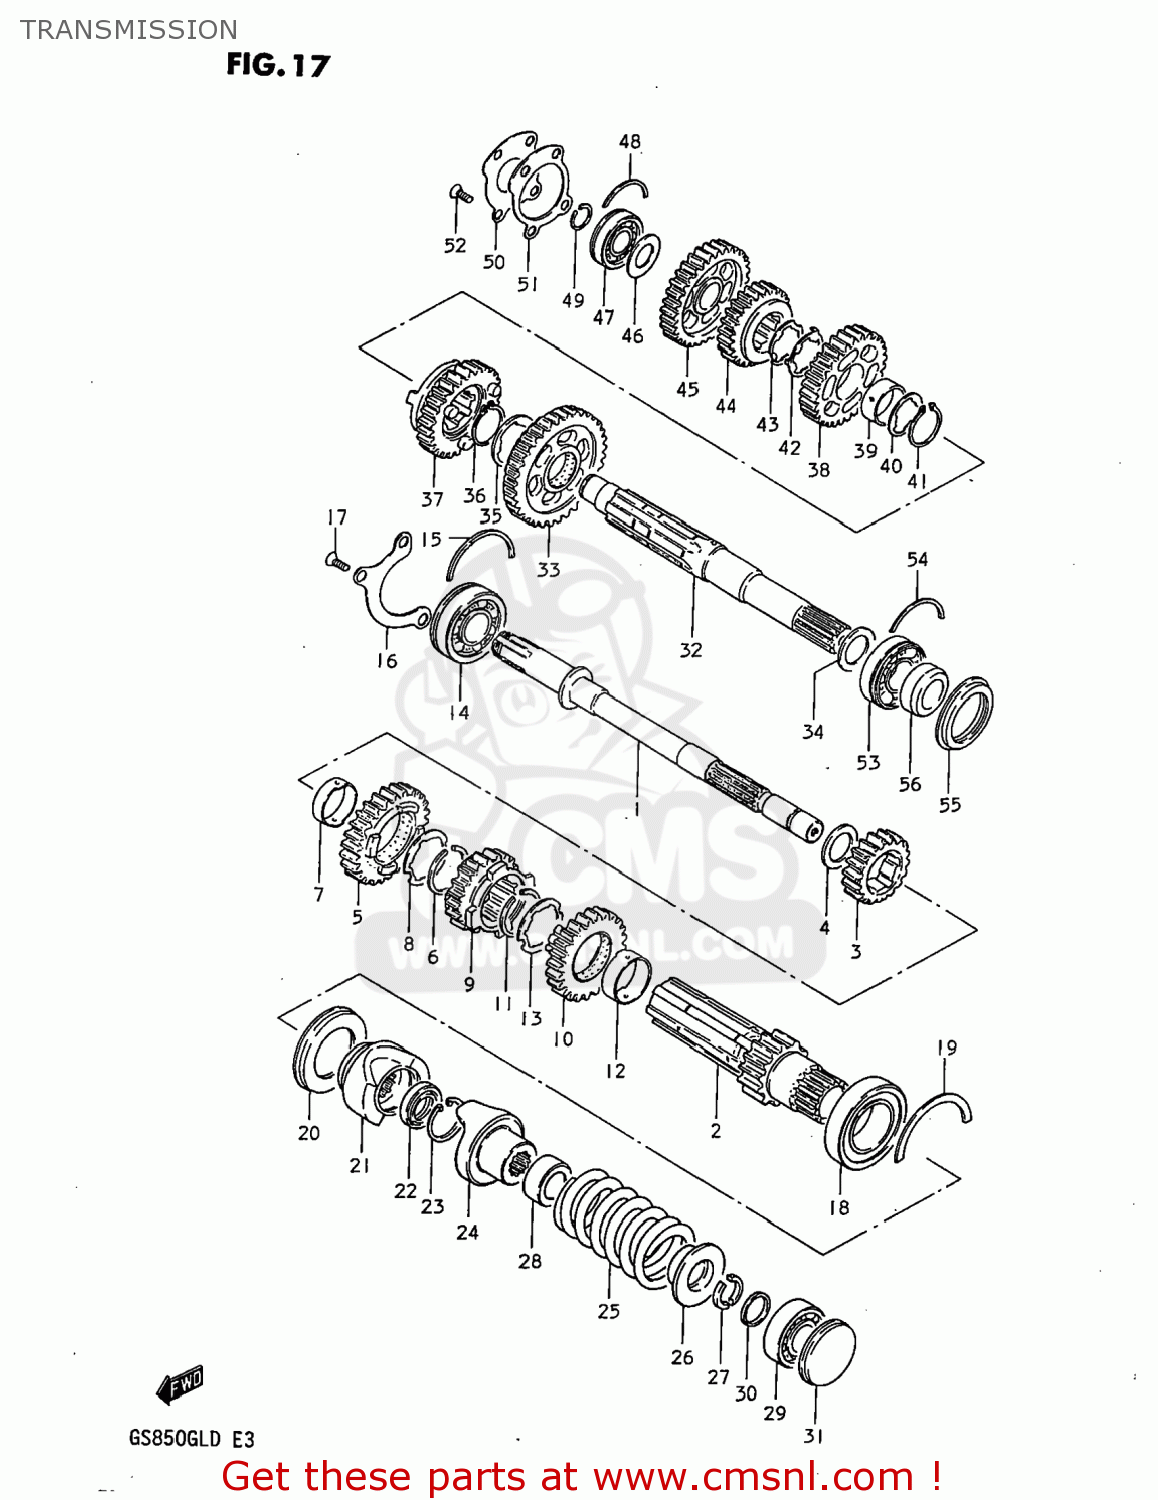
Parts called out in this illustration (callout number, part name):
1	SHAFT,COUNTER
2	SHAFT,OUTER COUNTER
3	GEAR,SECOND DRIVE
4	WASHER (21X35X2)
5	GEAR,5TH DRIVE(NT:26)
6	RING,SNAP
7	SPACER,DRIVE GEAR
8	LOCK WASHER,5TH DR GEAR SPACER
9	GEAR,THIRD DRIVE
10	GEAR,FOURTH DRIVE
11	RING,SNAP
12	SPACER,DRIVE GEAR
13	LOCK WASHER,5TH DR GEAR SPACER
14	BEARING(25X62X17)
15	C-RING
16	RETAINER,CNTR SHAFT BEARING
17	SCREW
18	BALL BEARING 32X58X13
19	C-RING
20	SEAL,OIL(40X58X7)
21	DOG,OUTPUT CAM
22	SEAL,OIL(20.6X31X6)
23	CIRCLIP
24	DOG,INPUT CAM
25	SPRING
26	STOPPER,CAM DOG
27	STOPPER,CAM DOG
28	GUIDE,CAM DOG SPRING
29	BEARING
30	SPACER (17X21X3.5)
31	PLUG
32	SHAFT,DRIVE
33	GEAR,FIRST DRIVEN
34	WASHER, LH
35	WASHER,LOCK
36	CIRCLIP
37	GEAR,FOURTH DRIVEN
38	GEAR,THIRD DRIVEN
39	BUSH,3RD DRIVEN GEAR
40	WASHER,LOCK
41	CIRCLIP
42	WASHER
43	WASHER,LOCK
44	GEAR,FIFTH DRIVEN
45	GEAR,SECOND DRIVEN
46	WASHER
47	BEARING(20X47X14)
48	C RING
49	CIRCLIP
50	PLATE,DRIVESHAFT
51	GASKET,DRIVESHAFT PLATE (MCA)
52	SCREW
53	BEARING
54	C RING
55	SEAL,OIL(35X52X6)
56	SPACER,DRIVESHAFT,LEFT
